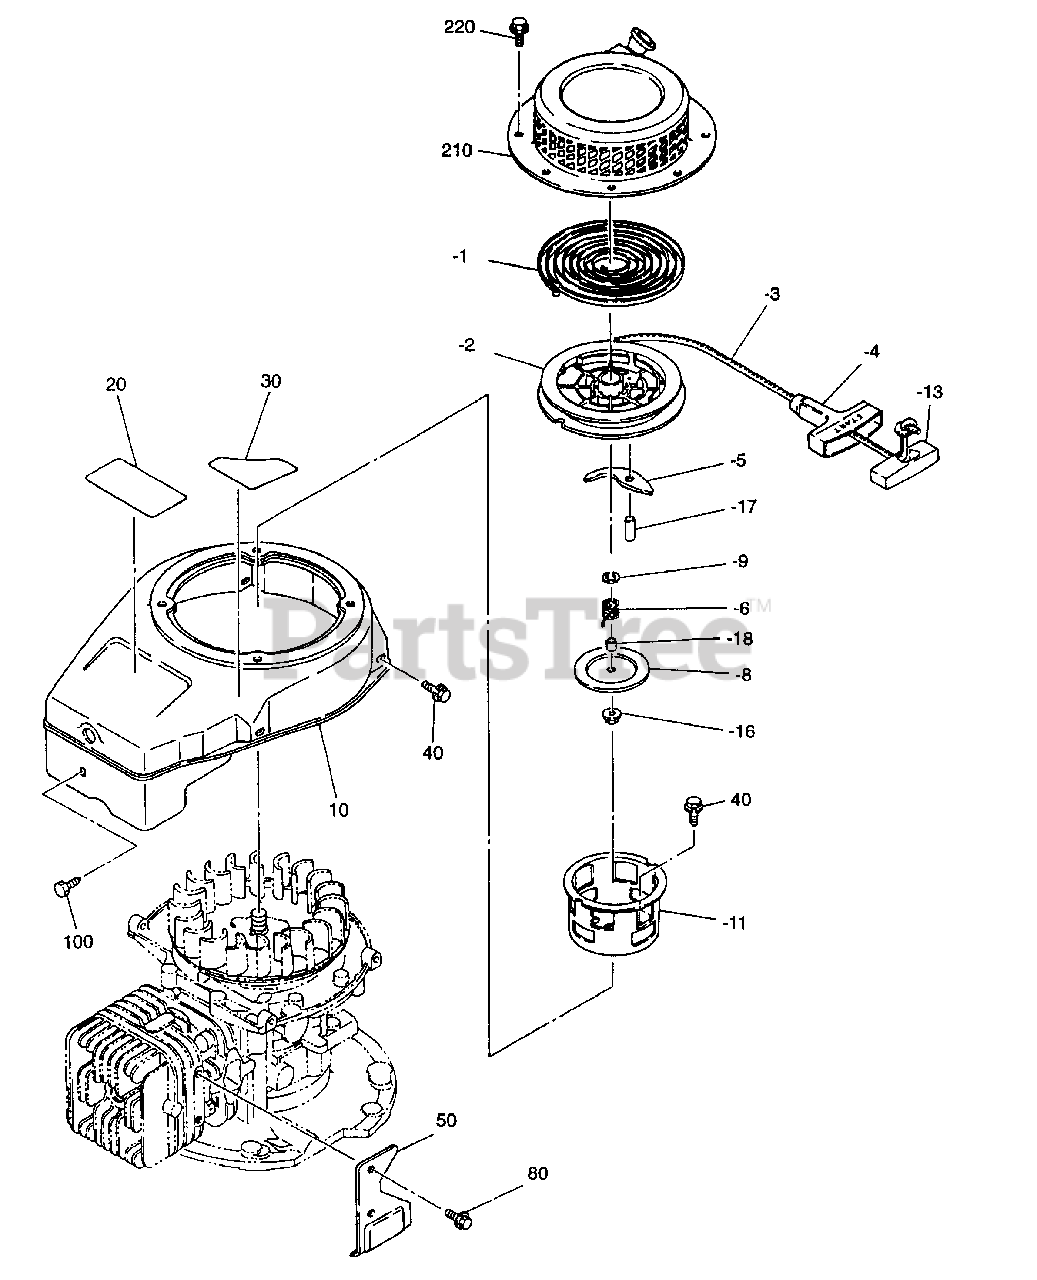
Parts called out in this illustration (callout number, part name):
1	SPIRAL SPRING
2	REEL (Pro-PoIy)
3	STARTER ROPE
4	STARTER KNOB
5	RATCHET V SNAPPER
6	FRICTION SPRING
8	FRICTION PLATE
9	THRUST WASHER
10	BLOWER HOUSING CP
11	STARTER PULLEY
17	RATCHET PIN
20	LABEL (TRADE MARK)
30	LABEL (WARNING)
40	BOLT AND WASHER ASSY
50	CYLINDER BAFFLE
80	FLANGE BOLT
100	TAPPING BOLT
210	RECOIL STARTER ASSY
220	FLANGE BOLT
